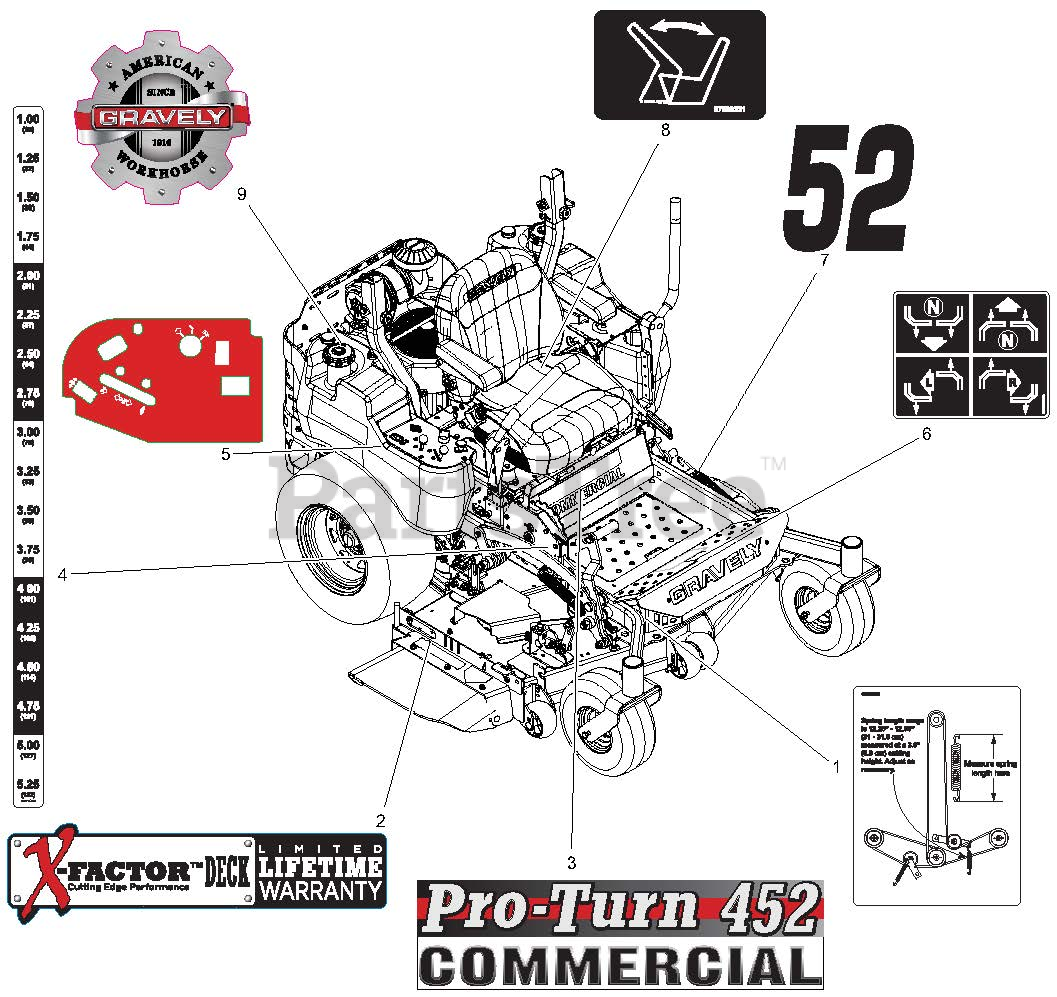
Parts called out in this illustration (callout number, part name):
1	DECAL, BELT ROUTING
2	DECAL, X-FACTOR DECK
3	DECAL, PT452
4	DECAL, PT400 HEIGHT OF CUT
5	DECAL, NON-EFI CONTROL PANEL
6	DECAL, INSTRUCTIONAL - STEERING
7	DECAL, 52"
8	DECAL, SEAT RELEASE
9	DECAL, GRAVELY HERITAGE-LARGE
